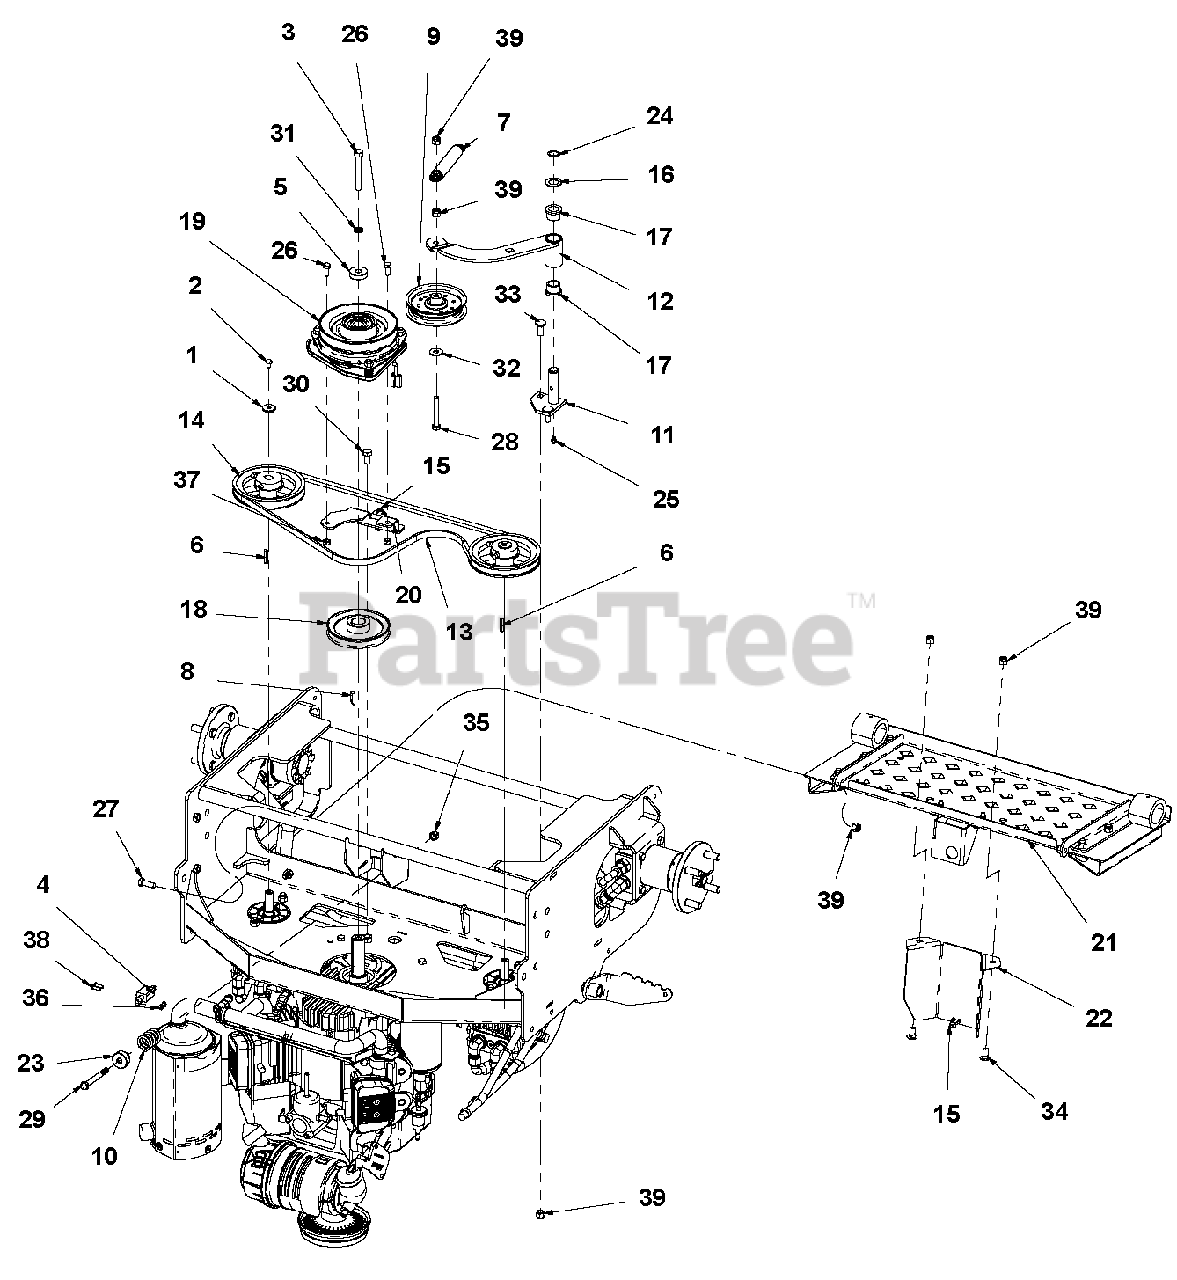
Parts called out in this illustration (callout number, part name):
1	Washer, .250 Wide Heavy Flat Y
2	Bolt, M6 x 1.00 x 10 Hex 8.8 Y
3	Bolt, Hex .44-20 x 2.25 Grade 5 EP80
4	Switch (N.0.)
5	Spacer, .468 x 1.38 x .375 Y
6	Key, M5 x M5 x M30 RD
7	Spring, External
8	Key, .250 x .250 x .995 TPR
9	Assembly, Idler 4"
10	Spring, COM 1.22 x .162 x 2.50 Y
11	Weldment, Pivot Idler Mount
12	Weldment, Idler Arm
13	Belt, Pump Drive
14	Assembly, Pump Pulley w/Set Screw
15	Cable Tie, .15 x 8.50
16	Bushing, MACH .750 x 1.25 x .048 Y
17	Bearing, FLG .750 x 1.00 x .750 BRNZ
18	Sheave, Engine 4.75 x 1.125
19	Clutch Assy, Ogura GT1A-AR03
20	Plate, Clutch Dog
21	Assembly, Foot Plate (See Foot Plate on page 22.)
22	Cover, OPC
23	Washer, Spring Y
24	Snap Ring, .750 x .042 External
25	Fitting, 1/4-28 STRGT Grease Zerk
26	Bolt, 5/16-18 x .750 Hex 5 Y
27	Bolt, 3/8-16 x 1.00 Hex 5 Y
28	Bolt, 3/8-16 x 2.50 Hex 5 Y
29	Bolt, 3/8-16 x 3.25 Hex 5 Y
30	Bolt, 7/16-14 x .750 Hex 5 Y
31	Washer, .438 Medium Spring Lock Y
32	Washer, .375 Regular Flat Y
33	Bolt, 3/8-16 x 1.00 Carriage Grade 5 Y
34	Bolt,3/8-16x3/4 Car Grade 5 LN Y
35	Nut, 3/8-16 Standard Hex Grade 5 Y
36	Locknut, 10-24 Nyloc Y
37	Locknut, 5/16-18 Nyloc Y
38	Screw, 10-24 x .625 PAN PHL MACY
39	Locknut, 3/8-16 Nyloc Y
